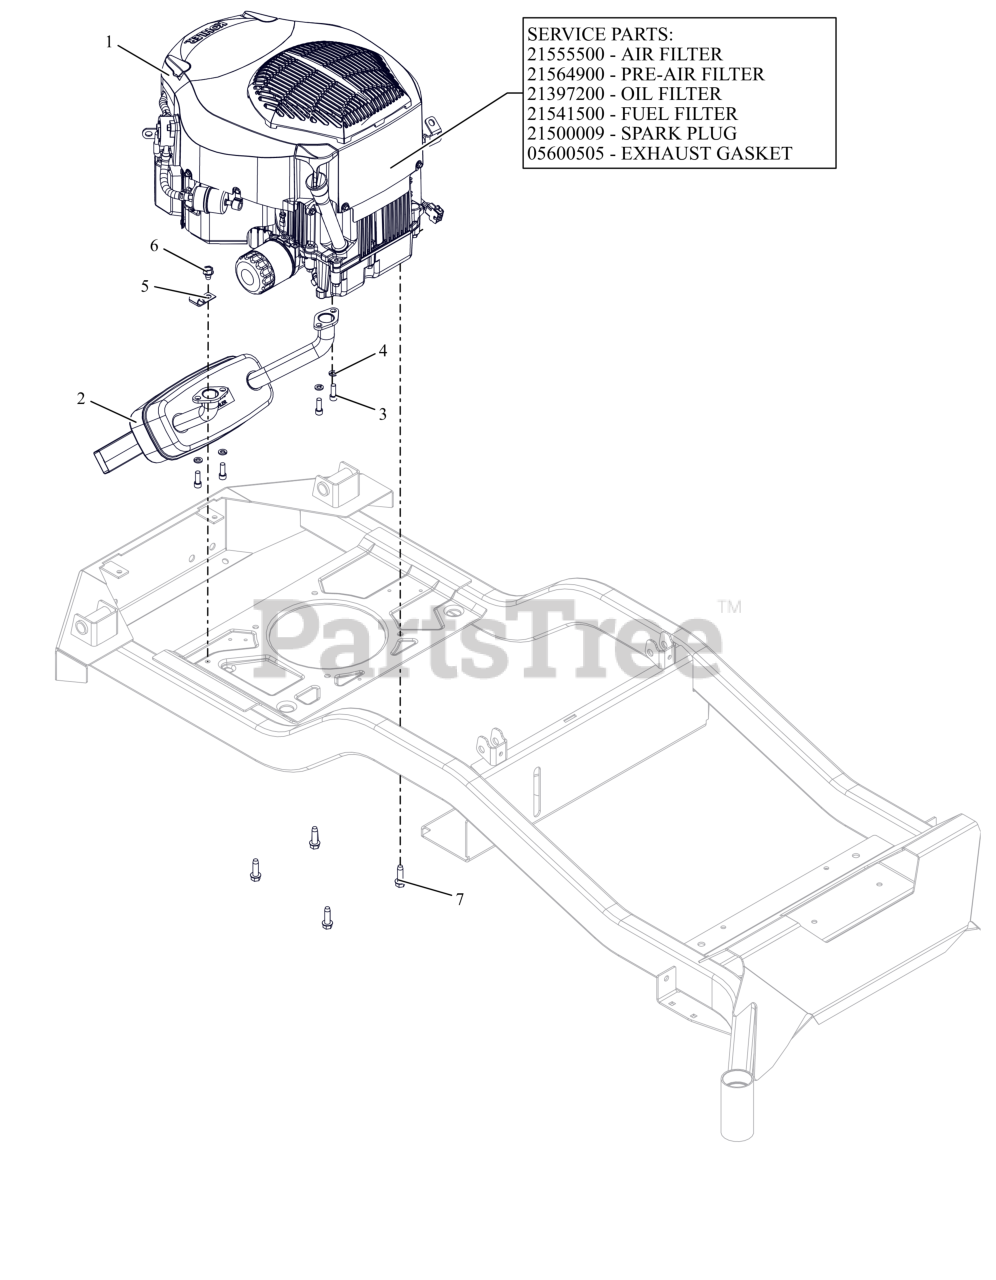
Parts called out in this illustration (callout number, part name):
1	ENGINE, KOHLER - KT730
1	AIR CLEANER, KOHLER
1	FILTER, OIL - KOH CV20
1	PRE-CLEANER, KOHLER
1	PLUG, SPARK KOHLER
1	FILTER, FUEL
1	GASKET, MUFFLER COURAGE TWIN
2	MUFFLER, KOHLER
3	SCR-CAP .31-18X.88 S/HD G8 ZCC
4	WSHR,LK-REG .312X.078 ZCC
5	J-CLAMP
6	SCR,TAP .375-16X.50 HWH TR ZCC
7	SCR,TAP .375-16X1.25HWH TR ZCC
